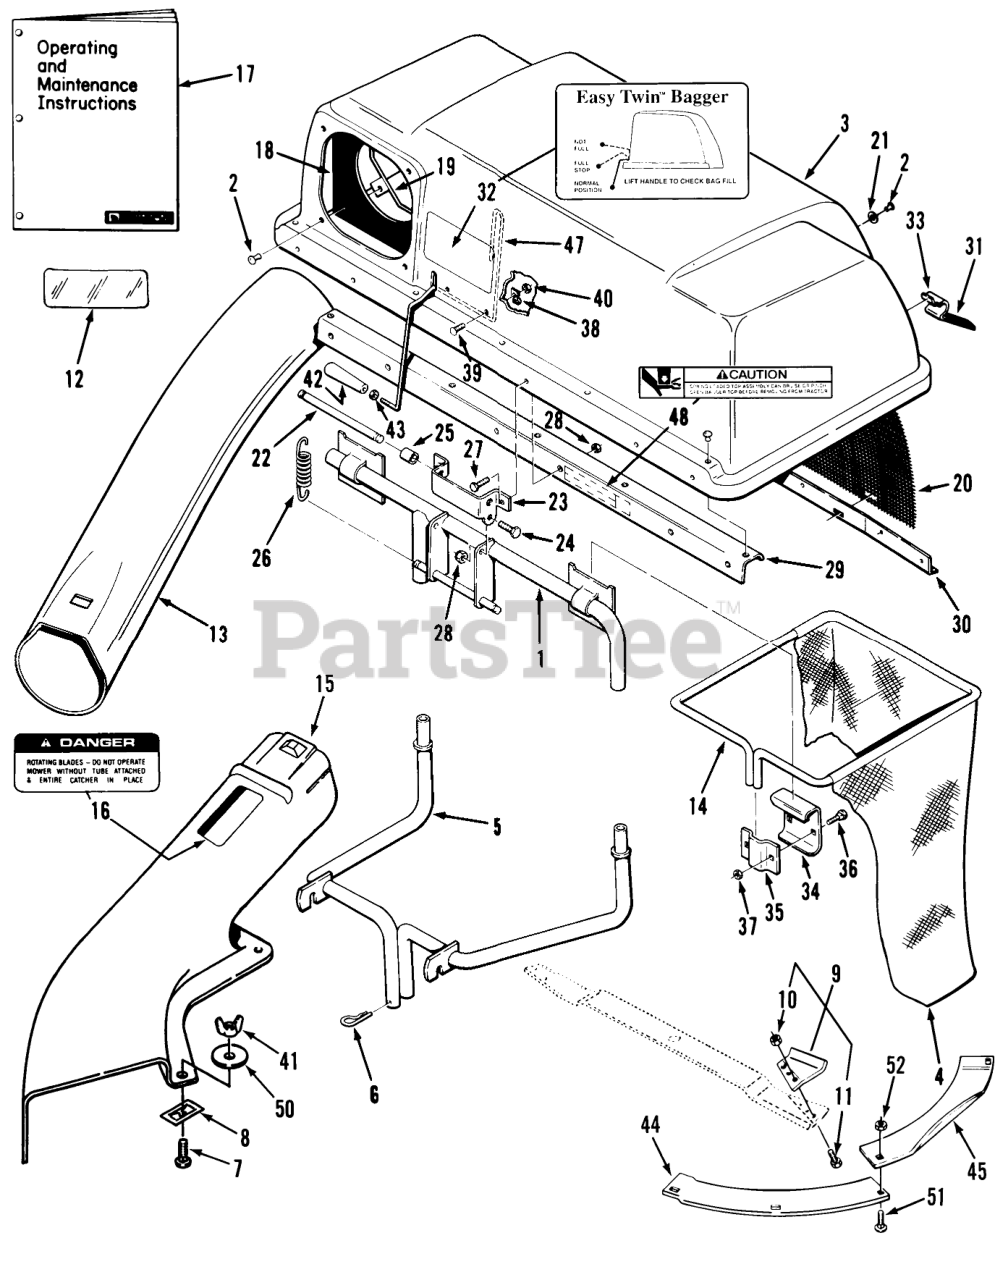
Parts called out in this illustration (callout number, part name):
1	FRAME ASM
2	RIVET-BLIND
3	TOP-BAGGER
4	BAG-18" DEPTH
5	ASM-QUICK ATTACH B
6	Hairpin
7	Bolt-Carriage
8	SPEED NUT 1/4-20
9	Lift Tab Kit (includes items 10 & 11)
10	BOLT 5/16-18X5/8
11	NUT-LOCK 5/16-18
12	DECAL-OVERLAY
13	CHUTE-BAGGER (L)
14	Bag Frame
15	Discharge Elbow (includes items 16)
16	DECAL-DANGER
17	Operating and Maintenance Instructions
18	Chute Seal
19	CLAMP-SEAL
20	SCREEN-BAGGER
21	Washer
22	PIN-SPRING
23	HINGE-BAG TOPB
24	Bolt
25	SPACER
26	SPRING-EXTENSION
27	BOLT
28	NUT
29	Bagger-Stiffener
30	SUPPORT-SCREEN B
32	Decal-Full Bag Test
33	Latch-Bag
34	Bag Hanger
35	Clamp
36	Bolt
37	Nut
39	Screw
40	Nut
41	Nut-Wing
42	HANDLE-TAPERED
43	Nut
44	PLATE MOWER RING B (NS)
45	PLATE MOWER B
47	FEELER-FILL, BAG
48	DECAL-CAUTION
50	WASHER
51	Bolt
52	Nut
